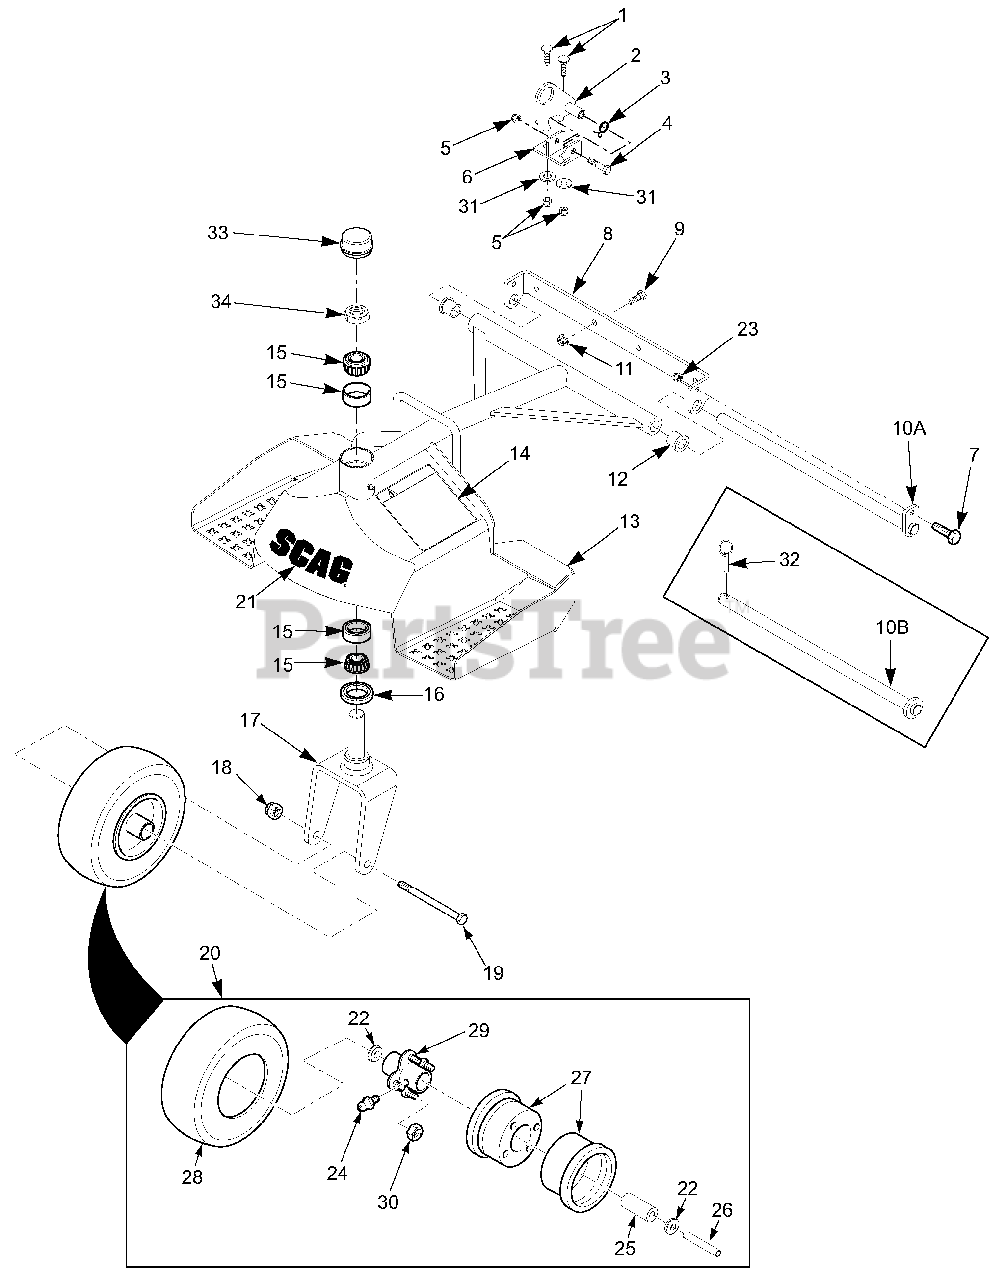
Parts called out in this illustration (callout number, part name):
1	Bolt, Carriage 3/8-16 x 1"
2	Latch Weldment
3	Spring, Latch
4	Bolt, Hex Head 3/8-16 x 2-1/4"
5	Nut, Elastic Stop 3/8-16
6	Mounting Bracket Weldment
7	Bolt, Hex Head 5/16-18 x 1"
8	Mounting Bracket, Sulky
9	Bolt, Hex Head 3/8-16 x 1"
10A	Mounting Shaft Weldment
10B	Mounting Shaft Weldment
11	Nut, Serrated Flange 3/8-16
12	Bushing, Bronze
13	Sulky Weldment
14	Decal, Warning
15	Bearing
16	Seal, 2" O.D. x 1.625" Bore
17	Yoke Weldment
18	Nut, Elastic Stop 1/2-13
19	Bolt, Hex Head 1/2-13 x 5-1/2"
20	Caster Wheel Assy.
21	Decal, Scag Logo
22	Bearing, Oilite
23	Nut, Elastic Stop 5/16-18
24	Grease Fitting, 45 Degree 1/4-28
25	Roller Bearing
26	Sleeve, Caster Wheel Bearing
27	Rim Pair, Caster Wheel
28	Tire Only, Caster Wheel
29	Hub Assy.
30	Tapered Nut, 5/16-24
31	Flatwasher, 3/8
32	Quick Pin
33	Cap, Grease
34	Nut, Elastic Stop 1.0"-14
